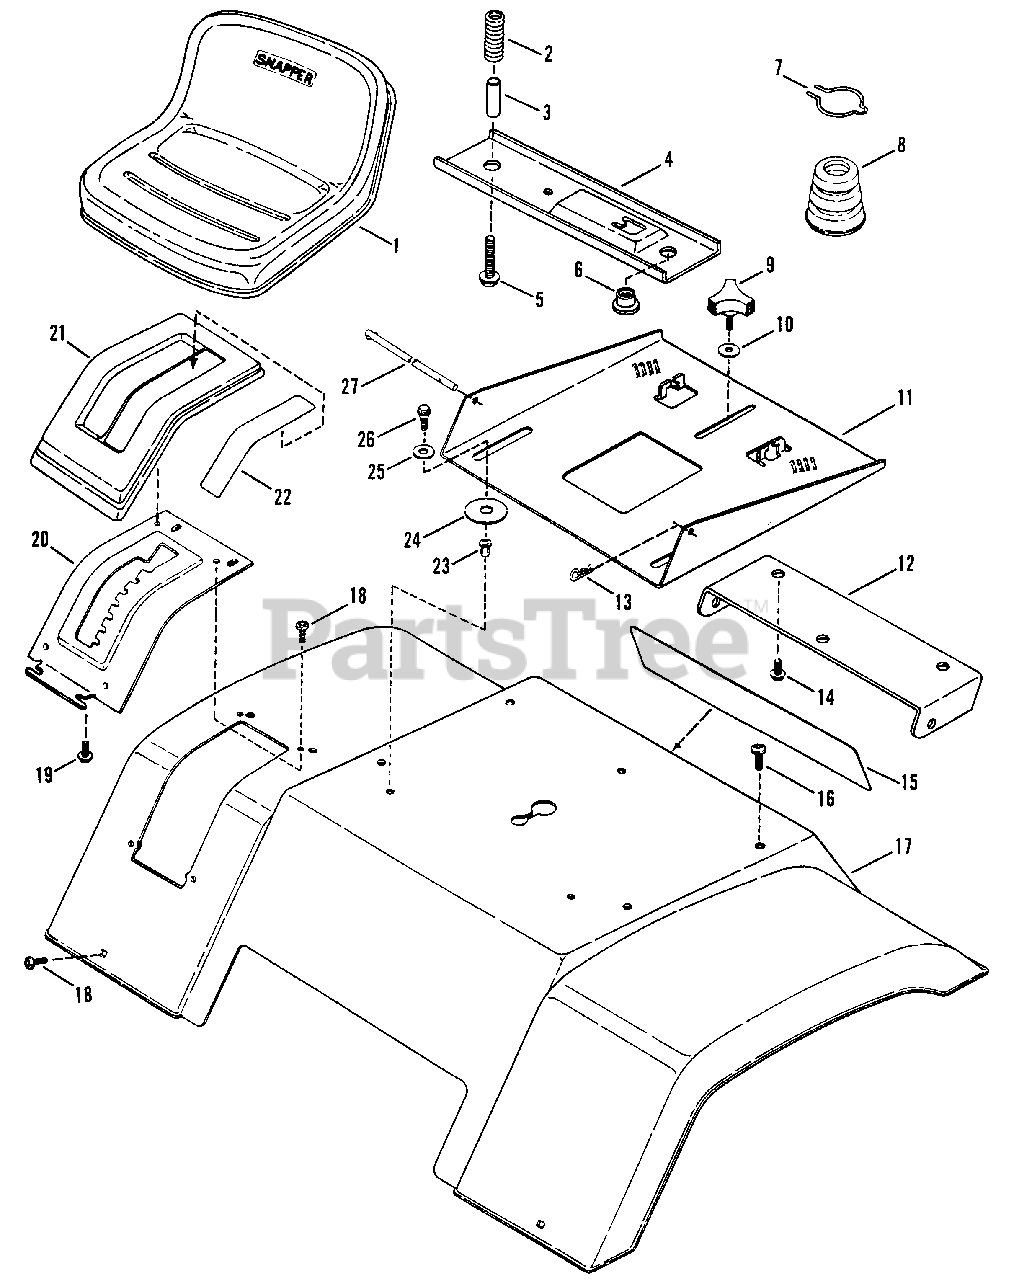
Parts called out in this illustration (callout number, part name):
1	SEAT, Operator's
2	SPRING, Seat Switch
3	SPACER, Seat
4	HOLDER, Seat Switch
5	BOLT, 5/16-18 x 2" Hex Flange Lock
6	BUSHING, Seat
7	CLIP, Seat Bumper
8	CUSHION, Seat
9	KNOB, Seat Adjustment
10	WASHER
11	SUPPORT, Seat
12	BRACKET, Seat Support
13	PIN, Hair
14	BOLT, 5/16-18 x 1/2" Hex Flange Lock
15	DECAL, SNAPPER, Molded Logo
16	SCREW, 5/16-18 x 7/8" Torx Head, Self-Tapping
17	FENDER, Rear
18	SCREW, 1/4-20 x 5/8" Torx Head, Self-Tapping
19	SCREW, #10-16 x 1/2" Self-Tapping
20	DETENT, Shift
21	COVER, Shift Detent
22	DECAL, Shift Cover
23	RIV-NUT, 5/16-18
24	SPACER
26	SCREW, Shoulder, 5/16-18 x 3/4"
27	ROD, Seat Hinge
